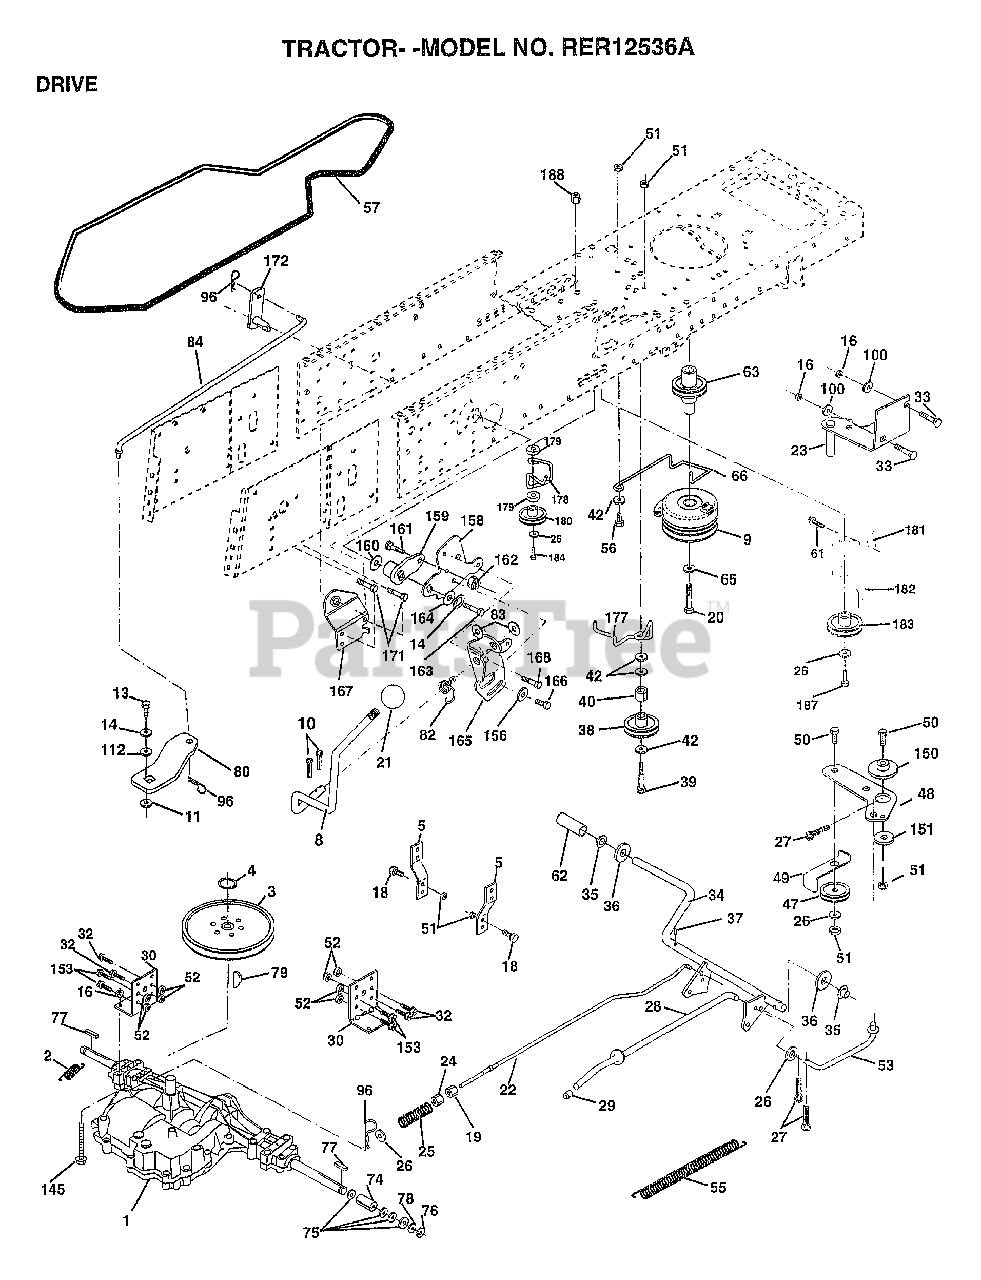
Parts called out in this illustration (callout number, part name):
2	SPRING.BRAKE.RETU
3	"PULLEY.TRANSAXLE.7"""
5	STRAP TORQUE
8	ROD.SHIFT.FENDER.ADJ.LT.CRD
9	CLUTCH.ELEC.EVX
10	PIN COTTER 1/8
11	WASH-SHFT PLT LT
13	BOLT.1/4-28.W/PAT
14	LOCKWASHER
16	NUT
18	BOLT
19	NUT
20	BOLT.7/16-20X4.25
21	KNOB T (1/2-HOLE)
22	ROD.BRAKE.PMST.CRD
23	BRACKET.CLUT.MTG.
24	NUT
25	SPRING ROD LT
26	WASHER
27	COTTER PIN
28	ROD.BRAKE.PARK.LT
29	PLUNGER CAP T
30	TRANSAXLE MTG BKT
32	BOLT
33	BOLT
34	SHAFT.ASM.PEDAL.FOOT.CRD
35	NYLON BEARING
36	WASHER LT
38	PULLEY.FLAT
39	BOLT
40	SPACER T
42	WASHER
48	BELLCRANK.CLUTCH
49	RETAIN BELT
53	"LINK, CLUTCH T"
55	"SPRING, RETURN LT"
57	"V-BELT.KEV.111"""
61	SCREW
62	PEDAL COVER T
63	PULLEY.CLUTCH.EVX
65	LOCKWASHER
66	KEEPER-BELT
74	SPACER AXLE
75	WASHER
76	E-RING LT
77	SQUARE KEY
78	WASHER
80	"ARM.SHIFT.20""TIRE"
82	"SPRING,TORSION"
83	WASHER
84	LINK.SHIFT.CRD
96	RETAINER M
100	WASHER M
112	WASHER LT
145	BOLT.HEX.FLGHD
150	BUSHING.BELLCRANK.GRD.DR
151	WASHER
156	WASHER.SRRTD.5/16
158	BRKT.SHIFT.MOUNT
159	HUB.SHIFT
160	WASHER
161	BOLT T
164	WASHER.5/8X.281X10GA
165	BRKT.PIVOT.LEVER
166	SCREW.5/16-18X5/8
167	BRKT.SUPT.SHIFT.CRD
168	BOLT.SHOULDER.5/16-18X.561
171	SCREW LT
172	SHAFT.ASM.SHIFT.FRT.CRD
177	KEEPOER.FLAT.IDLER
178	KEEPER.BELT.IDLER
179	WASHER
180	PULLEY.FLAT.IDLER
181	BRKT.IDLER.GRD.DR.CRD
182	"KEEPER.BELT.2.5"".OD.CRD"
183	PULLEY.V-IDLER
184	SCREW.HXWSH.3/8
187	SCREW
